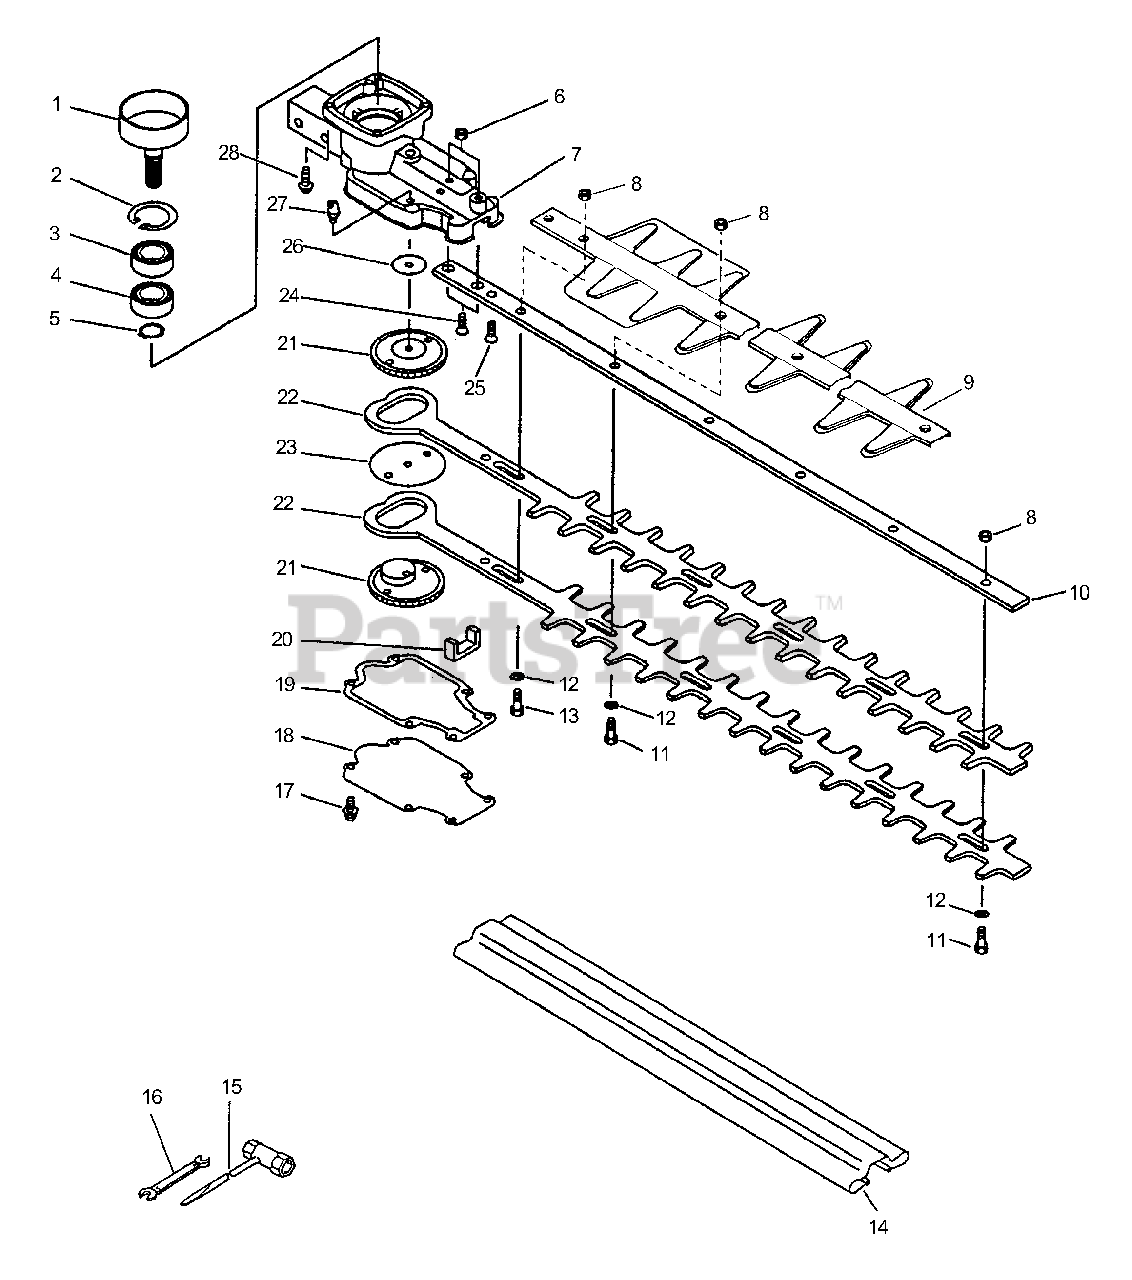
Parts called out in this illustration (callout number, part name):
1	DRUM, CLUTCH
2	RING, SNAP 35
3	BEARING, BALL 6202
4	BEARING, BALL 6202
5	RING, SNAP 14
6	NUT, HEX M6
7	CASE, GEAR
9	STIFFENER
10	SUPPORT, BLADE
11	BOLT 6×18
12	WASHER 6.5×15.5×0.6
13	BOLT M6×35
14	COVER, BLADE
15	T-WRENCH 13×19×180
16	SPANNER 8×10
17	BOLT 4×12
18	LID, GEAR CASE
19	GASKET, GEAR CASE
21	GEAR, SPUR
22	BLADE, TRIMMER
23	WASHER 6.7×54×0.38
24	SCREW 6×30
25	SCREW 5×30
26	WASHER 6.5×30×0.2
27	FITTING, GREASE
28	BOLT 4×16
